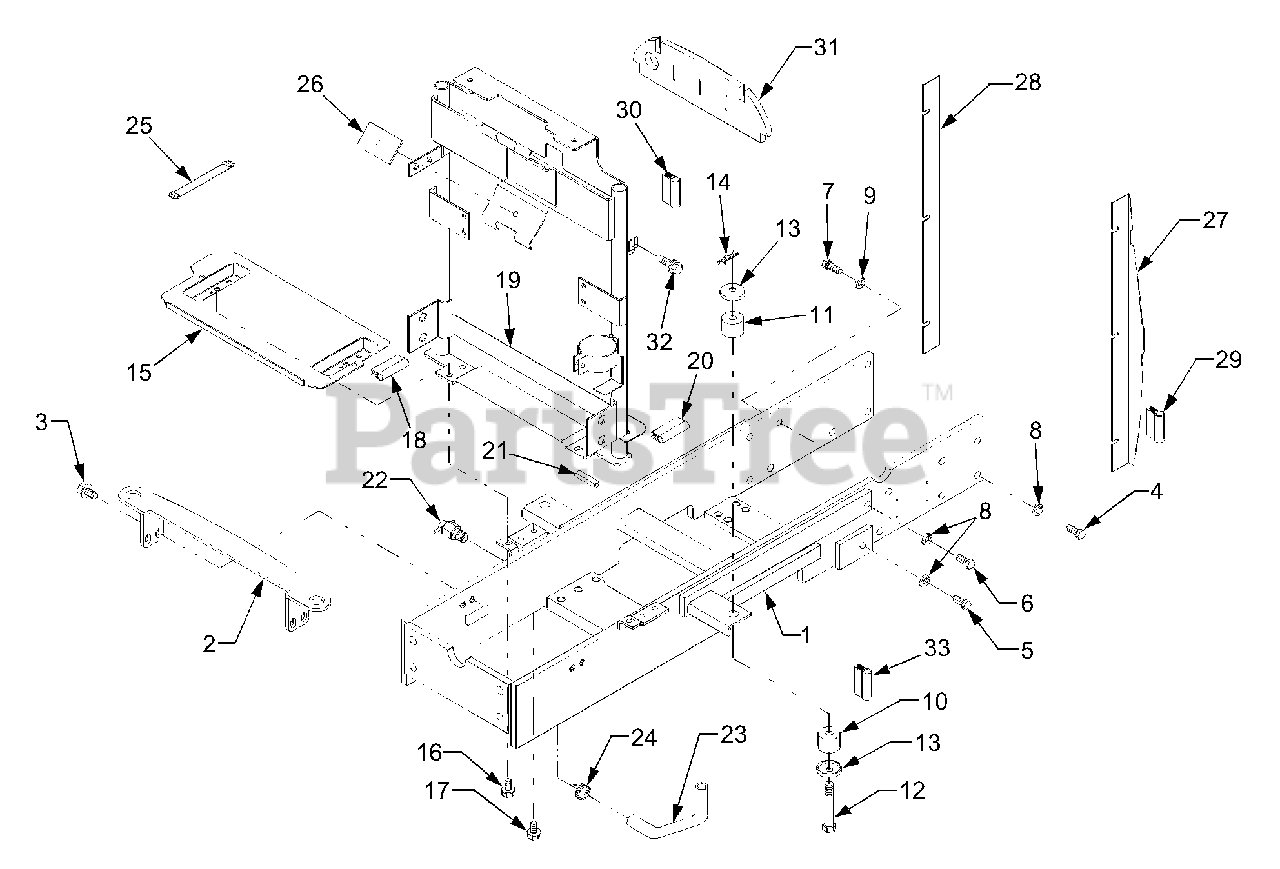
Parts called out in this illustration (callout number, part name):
1	Frame, Front Axle
4	Bolt
8	Washer, Spring
9	Washer, Spring
15	Support, Battery
19	Support, Aircleaner
22	Cock, Drain
25	Band, Aircleaner)
31	Rubber, Cushion
